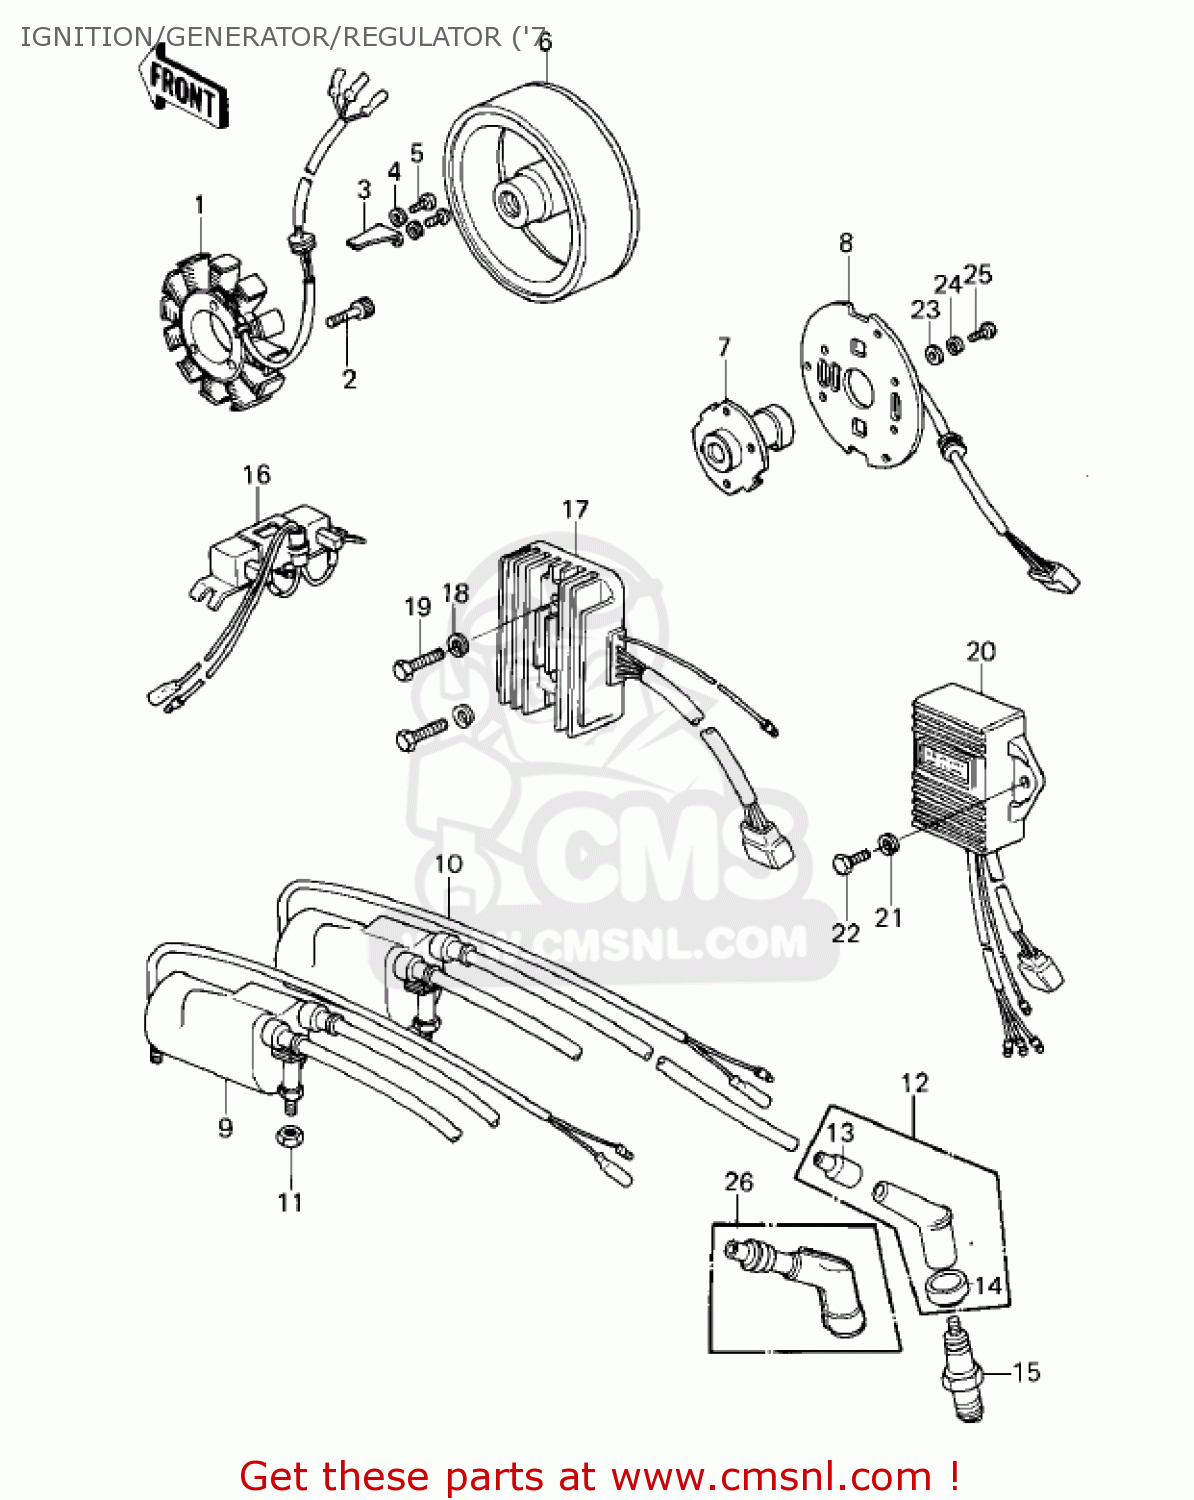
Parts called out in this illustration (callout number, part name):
1	STATOR
2	BOLT,SOCKET,5X25
3	CLAMP,GENERATOR LEAD
4	WASHER-SPRING,5MM
5	SCREW-PAN-CROS
6	ROTOR
7	GOVERNOR-BREAKER
8	COIL-PULSING
9	COIL-IGNITION,#1&4
10	COIL-IGNITION,#2&3
11	NUT,LOCK,6MM
12	CAP-ASSY-PLUG
13	GROMMET,SPARK PLUG CP
14	GROMMET,PLUG CAP
16	RESISTOR
17	REGULATOR-VOLTAGE
18	WASHER-SPRING,6MM
19	BOLT-UPSET,6X25
20	IGNITER
21	WASHER-SPRING,6MM
22	BOLT UPSET,6X16
23	WASHER-PLAIN-SMALL,5M
24	WASHER-SPRING,5MM
25	SCREW-PAN-CROS
26	CAP-ASSY-PLUG
